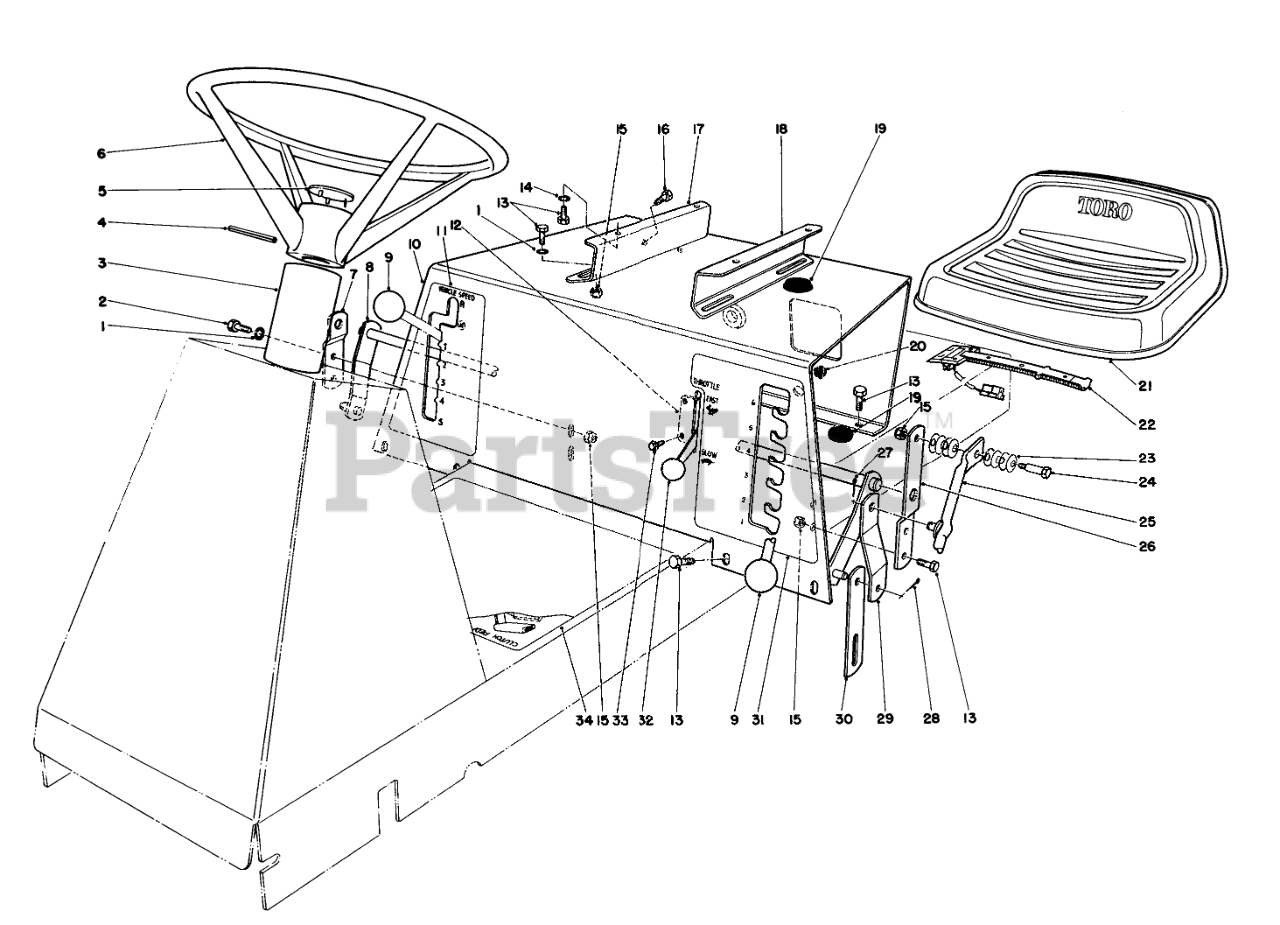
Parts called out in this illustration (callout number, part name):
1	WASHER-PLAIN
2	SCREW-HH
3	STRG. SHAFT COVER
4	PIN-ROLL
5	Cap-Steering Wheel
6	Steering Wheel (Incl. Ref. #5)
7	Bracket H.O.C Support
8	HOC LEVER WA B
10	Support Seat
11	Decal-Transmission
12	Throttle Control (Incl. Ref. #32)
13	SCREW-HH
14	WASHER-LOCK
15	NUT-LOCK, NI
16	SCREW-HH
17	Bracket-Seat RH.
18	Bracket-Seat LH.
19	GROMMET
20	GROMMET
21	Seat
22	SWITCH-SEAT
23	WASHER-BELLEVILLE
24	BOLT-SHOULDER
25	HOC LEVER WA B
26	Bracket
27	PIN-COTTER
28	PIN-COTTER
29	Bracket-Height Of Cut Engagement
30	Link-Deck Suspension
31	Decal-Height Of Cut
32	KNOB-CONTROL
33	SCREW-HWHTF
34	INSTRUCTION DECAL
